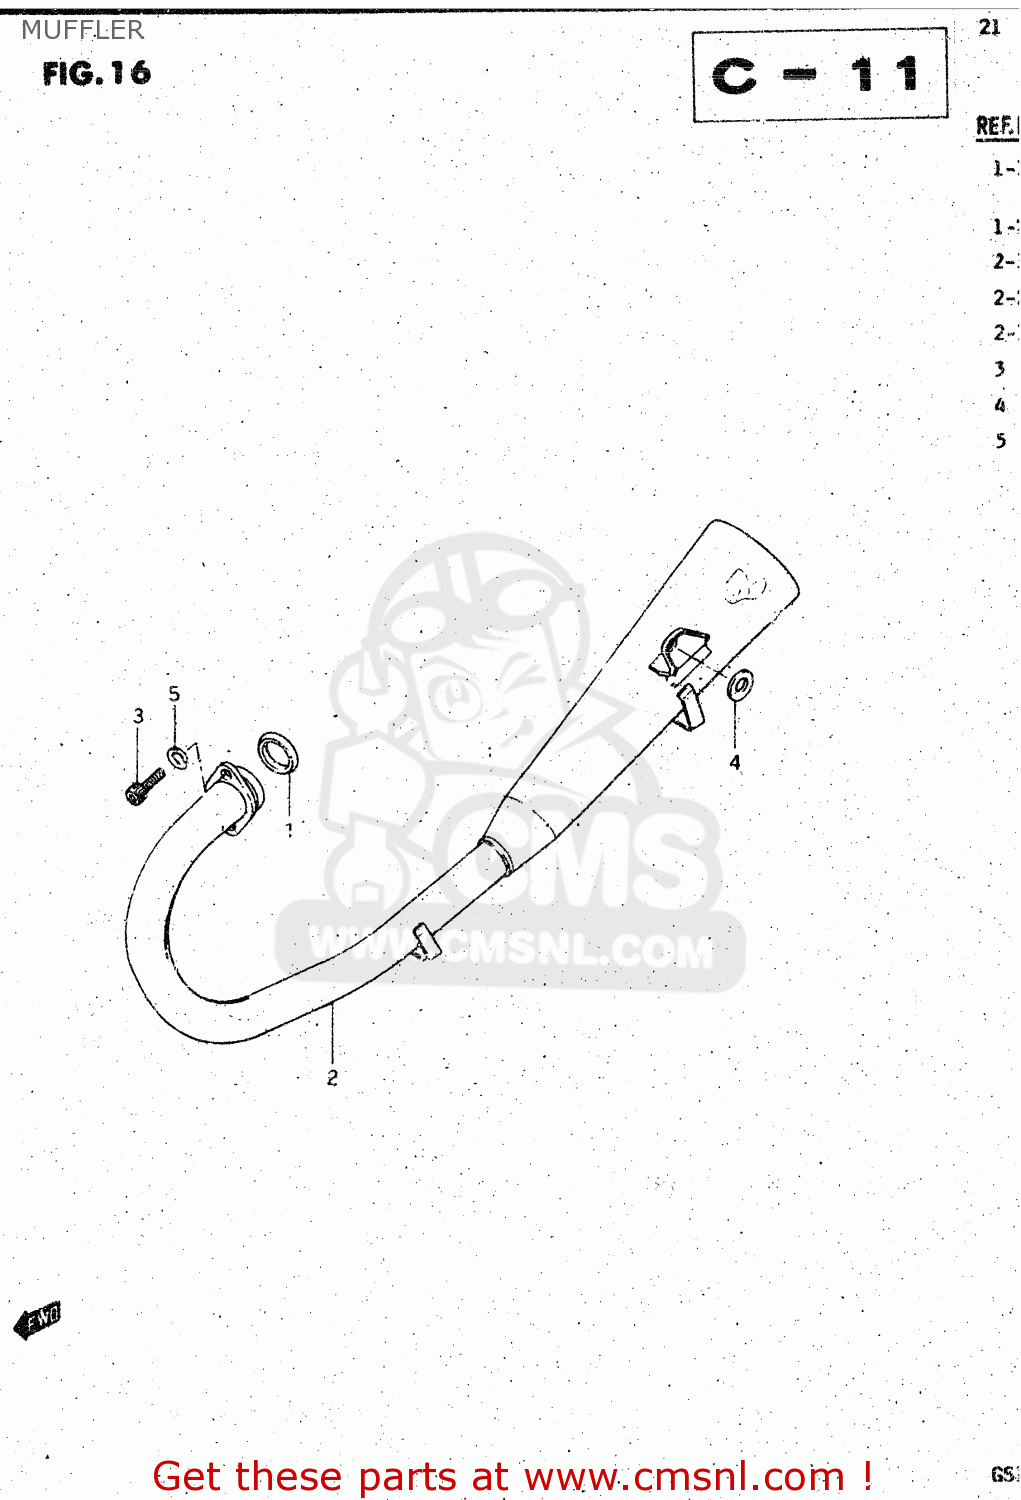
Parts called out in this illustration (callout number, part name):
1	GASKET,EXHAUST (NAS)
2	MUFFLER ASSY
3	BOLT
4	WASHER
5	WASHER
